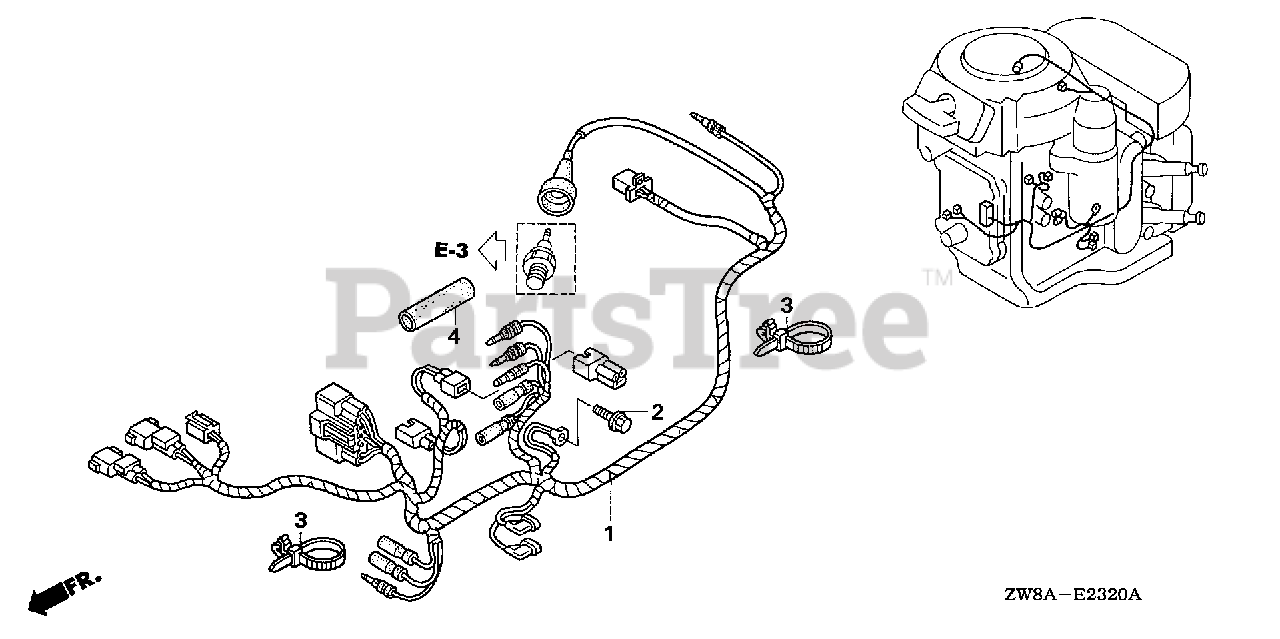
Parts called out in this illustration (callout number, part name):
1	WIRE HARNESS ASSY.
2	BOLT, FLANGE (6X12)
3	BAND, WIRE (95MM)
4	TUBE, RUBBER (11.5X14.5)
